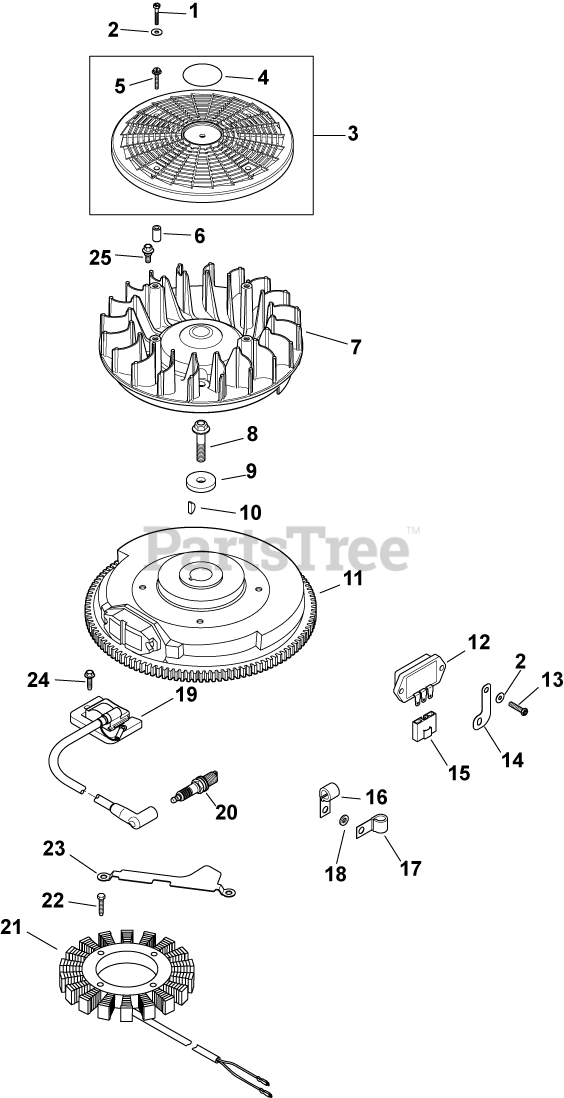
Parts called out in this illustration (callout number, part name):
1	SCREW, SLT HD CAP M4X0.7X25
2	WASHER, FLAT 3/16"
3	KIT, GRASS SCREEN
4	DECAL, GRASS SCREEN USE 24 113 499-S
5	SCREW, FLG SEMS M4X.7X25
6	SPACER - DISCONTINUED
7	FAN (DOMED)-USE 24 157 17-S
8	SCREW, FLG M10X1.5X45 - (#25086361S)
9	WASHER, FLAT 13/32"
10	KEY, 3/16" X 5/8"
12	REG/RECT-15 AMP (KM)-USE 41 403 10-S
13	SCREW, PHL HD #11-16X7/8"
14	BRACKET, GROUND STRAP USE 24 518 12-S
15	CONNECTOR
16	CLIP, CABLE
18	WASHER, FLAT 1/4" (O.D. 1/2")
19	KIT, MODULE IGNTN (CDI FIXED)
20	PLUG, SPARK (PRO SERIES)
21	KIT, 15 / 20 AMP STATOR
22	SCREW, M5X0.8X25 - (#25086402S)
23	BRACKET, STATOR WIRE
24	SCREW, FLG THD FRM M5X.8X20-(#25086399S)
25	BOLT, SHOULDER
